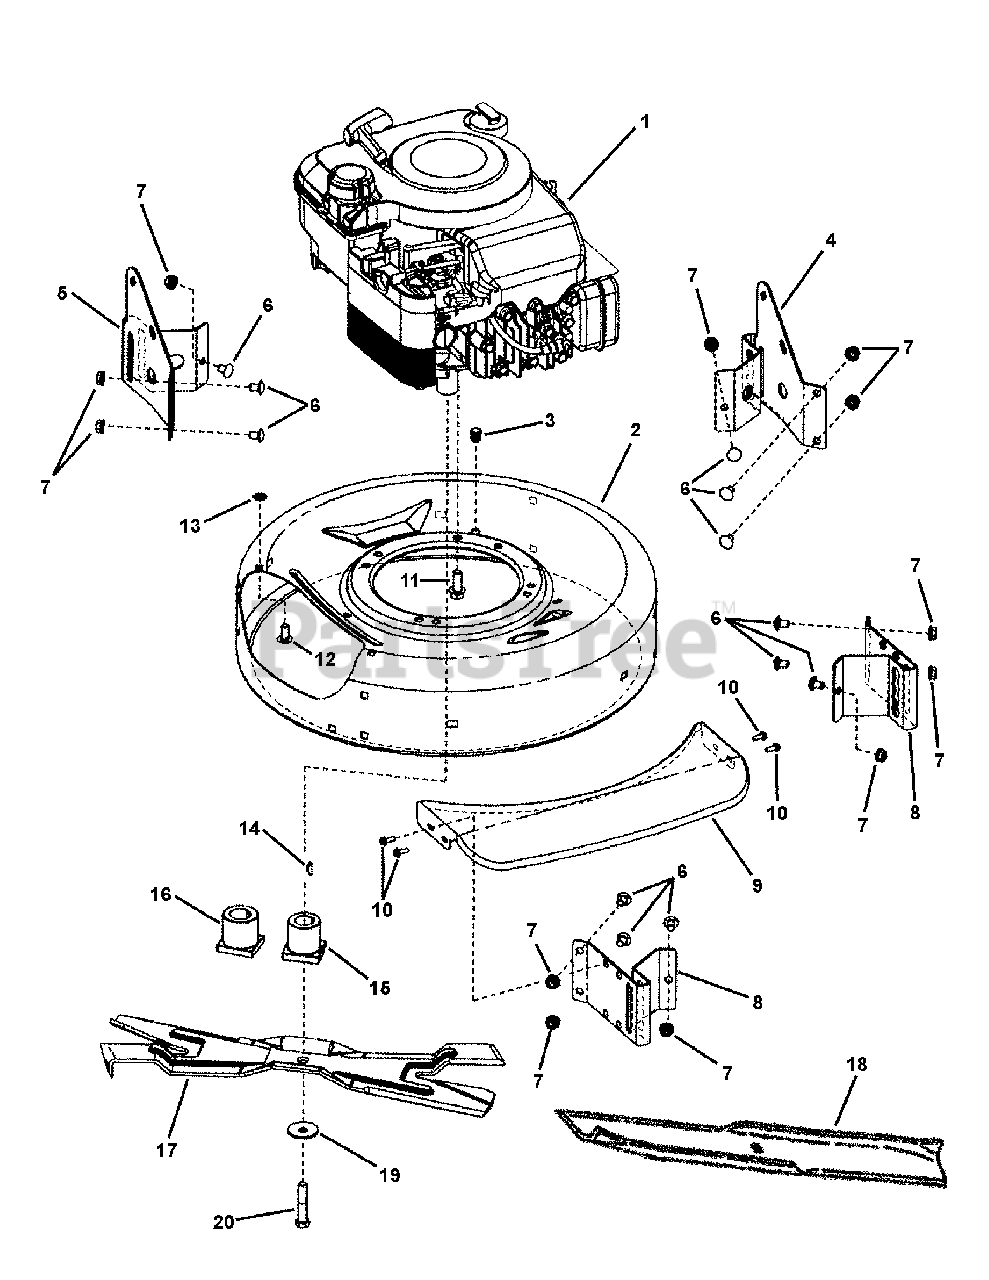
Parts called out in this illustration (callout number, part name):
1	* ENGINE, 4HP B&S Quattro
1	* ENGINE, 4.5HP B&S Quantum
1	* ENGINE, 4.5HP Quantum
1	* ENGINE, 5.5HP B&S Quantum
1	* ENGINE, 5.5HP B&S Quantum Euro
1	* ENGINE, 6HP B&S Quantum Euro
1	* ENGINE, 6.25GT B&S Quantum
2	ASSEMBLY, 19" Cutting Deck
3	PLUG, Hole (Polyethylene)
4	BRACKET, Rear Wheel Left Side
5	BRACKET, Rear Wheel Right Side
6	BOLT, 5/16-18 x 1/2" Short Neck Carriage, GR 5
7	NUT, 5/16-18 Hex Flange Lock, GR 5
8	BRACKET, Front Wheels R & L
9	PLATE, 19" Deck Front
10	SCREW, #10-24 x 1/2" Hex Washer Head Self-Tap
11	SCREW, 3/8-16 x 1" Hex Washer Head Self-Tap
12	BOLT, 5/16-18 x 3/4" Short Neck Carriage, GR 5
13	RETAINER, 5/16 Bolt (Black)
14	KEY, #505 Hi-Pro
15	HUB, Blade 7/8" Internal Dia.
16	HUB, Blade 25mm Internal Dia. (w/integral key)
17	BLADE, 19" Ninja (quad edge)
18	BLADE, 19" Mulching
19	WASHER,Cone
20	SCREW, 3/8-24 x 2" Hex Head Ca, GR 5
